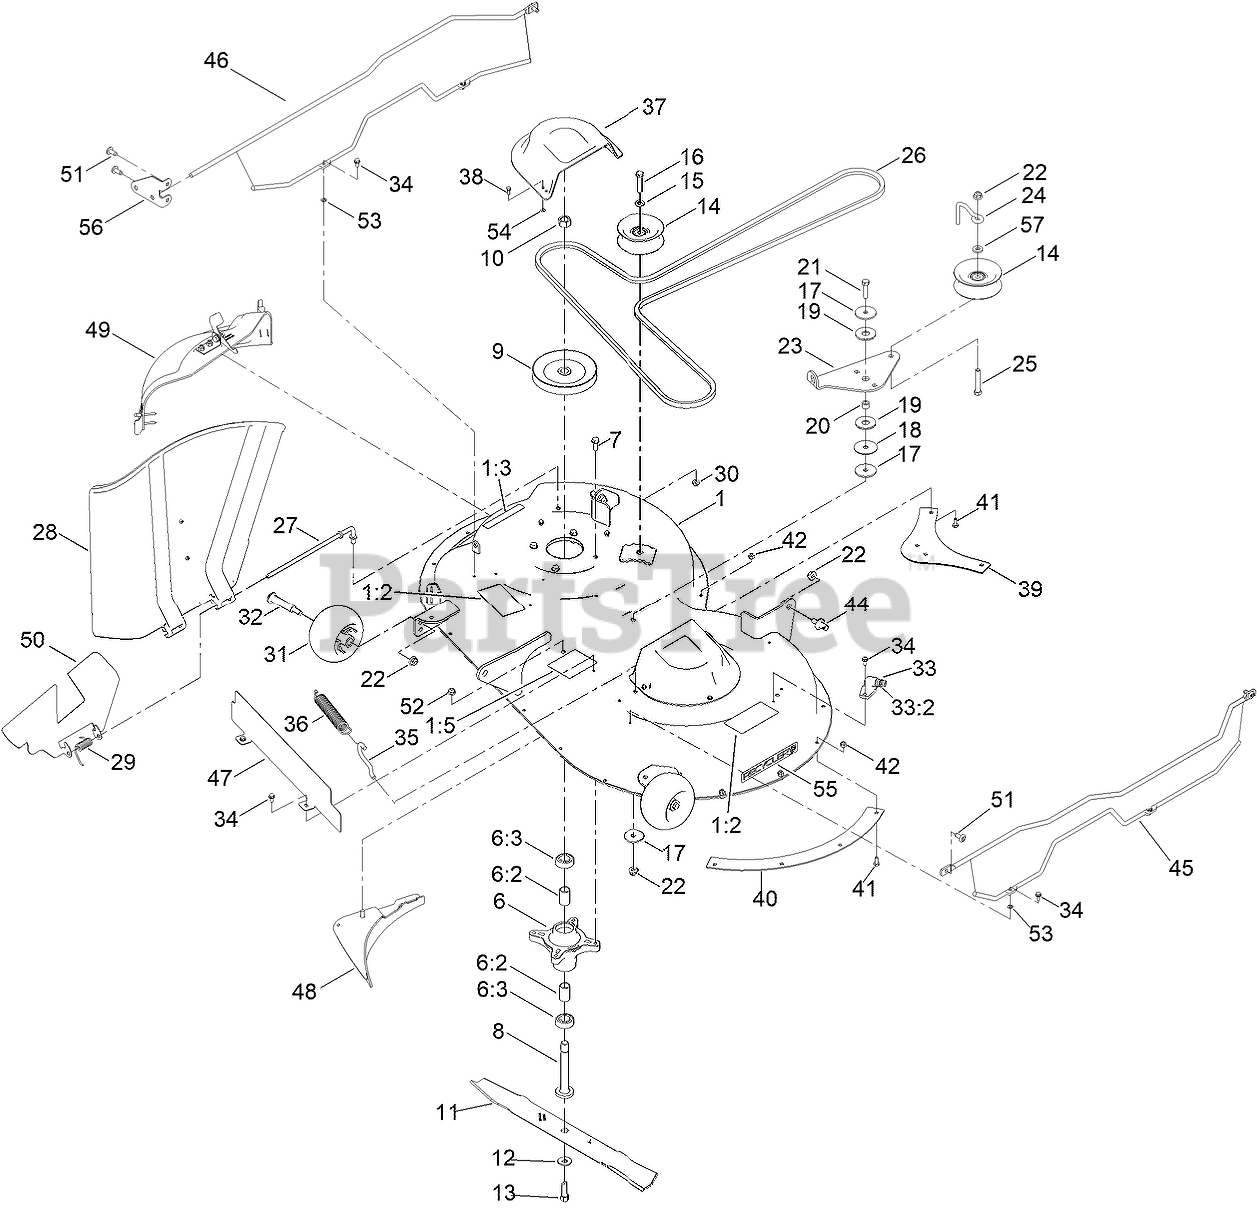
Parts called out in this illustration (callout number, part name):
1	42 INCH DECK AND DECAL ASM
1:2	DECAL-DANGER, DECK
1:3	DECAL-DANGER
1:5	DECAL-ROUTING, BELT
6	SPINDLE ASM
6:2	SPACER
6:3	BEARING-BALL
7	SCREW-TAPTITE
8	SHAFT-SPINDLE
9	Pulley
10	Nut-Hex
11	BLADE-MULCH
12	WASHER-BELLEVILLE
13	SCREW-HH
14	PULLEY-IDLER, FLAT
15	WASHER-FLAT
16	SCREW-HH
17	Washer
18	WASHER
19	WASHER-FRICTION, COMPOSITE
20	SPACER
21	SCREW-HH
22	NUT-HF, NI
23	ARM-IDLER
24	BELT GUIDE - IDLER
25	SCREW-HH
26	V-BELT
27	ROD-PIVOT
28	DEFLECTOR
29	SPRING-TORSION
30	NUT-HEX
31	ROLLER-SCALP, ANTI
32	BOLT-SHOULDER
33	FITTING-WASHOUT
33:2	O-RING
34	SCREW-HWH
35	HOOK-RETURN SPRING
36	SPRING-EXTENSION
37	COVER-BELT
38	SCREW-TAPTITE
39	BAFFLE-BLOWOUT, REAR
40	BAFFLE-BLOWOUT, SIDE
41	SCREW-HH
42	NUT-HEX
44	PIN-DECK
45	LEFT GUARD ASM
46	RIGHT GUARD ASM
47	SHIELD-FROUNT
48	BAFFLE-CLIPPING
49	42 INCH MULCH PLUG ASM
50	DEFLECTOR-INSERT
52	NUT-HF
53	NUT-RETAINING
54	NUT-RETAINING
55	DECAL-RECYCLER
56	PLATE-MOUNT, GUARD
57	SPACER-HUB, BLOWER
